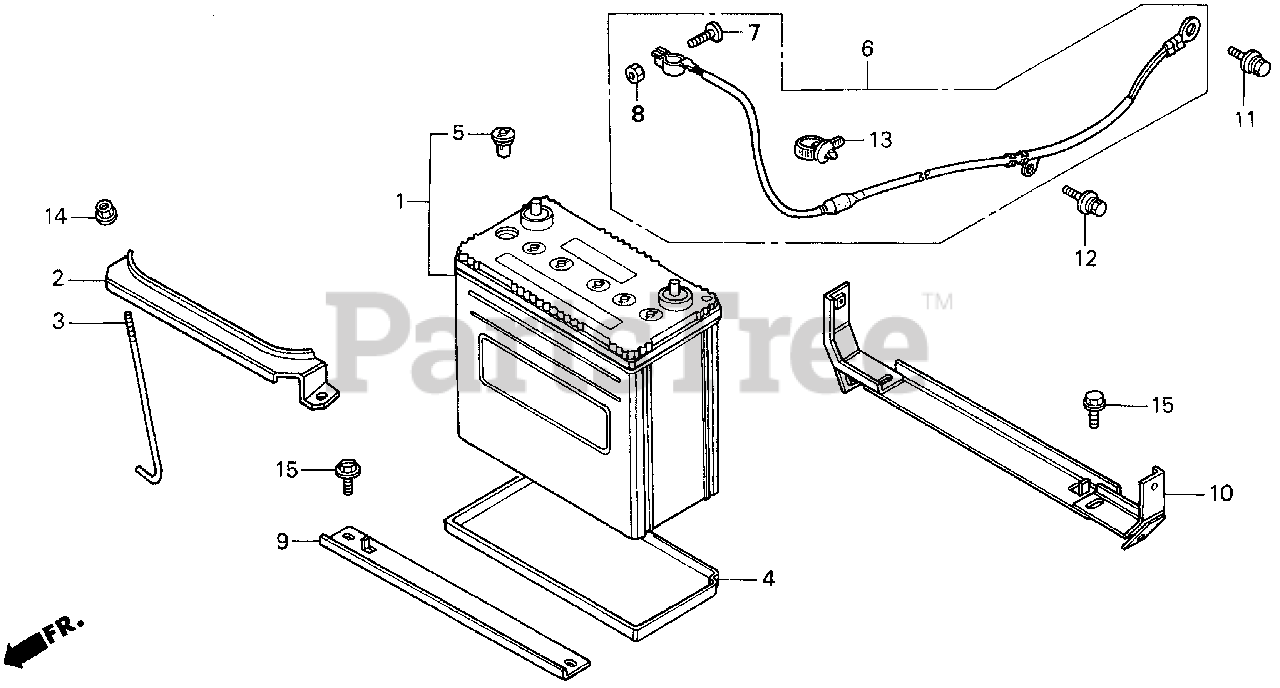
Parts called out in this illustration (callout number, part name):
1	BATTERY ASSY. (55B24L S-MF) (PANASONIC) (NOT AVAILABLE)
1	BATTERY ASSY. (55B24L S-MF) (YUASA) (NOT AVAILABLE)
2	PLATE, BATTERY SETTING (NOT AVAILABLE)
3	BOLT, BATTERY SETTING (225MM)
4	BOX ASSY., BATTERY
5	PLUG, VENT (MF) (FURUKAWA)
5	PLUG, VENT (MF) (PANASONIC)
6	CABLE ASSY., GROUND
7	BOLT, BATTERY TERMINAL (SUMITOMO)
7	BOLT, BATTERY TERMINAL
8	NUT, BATTERY TERMINAL (SUMITOMO)
9	PLATE, FR. BATTERY BASE
10	PLATE, RR. BATTERY BASE
11	BOLT, GROUND (6X19) (SN)
12	BOLT, GROUND (6X16) (SN)
13	BAND, WIRE HARNESS (110MM) (BROWN)
14	NUT, FLANGE (6MM)
15	BOLT, FLANGE (6X12)
